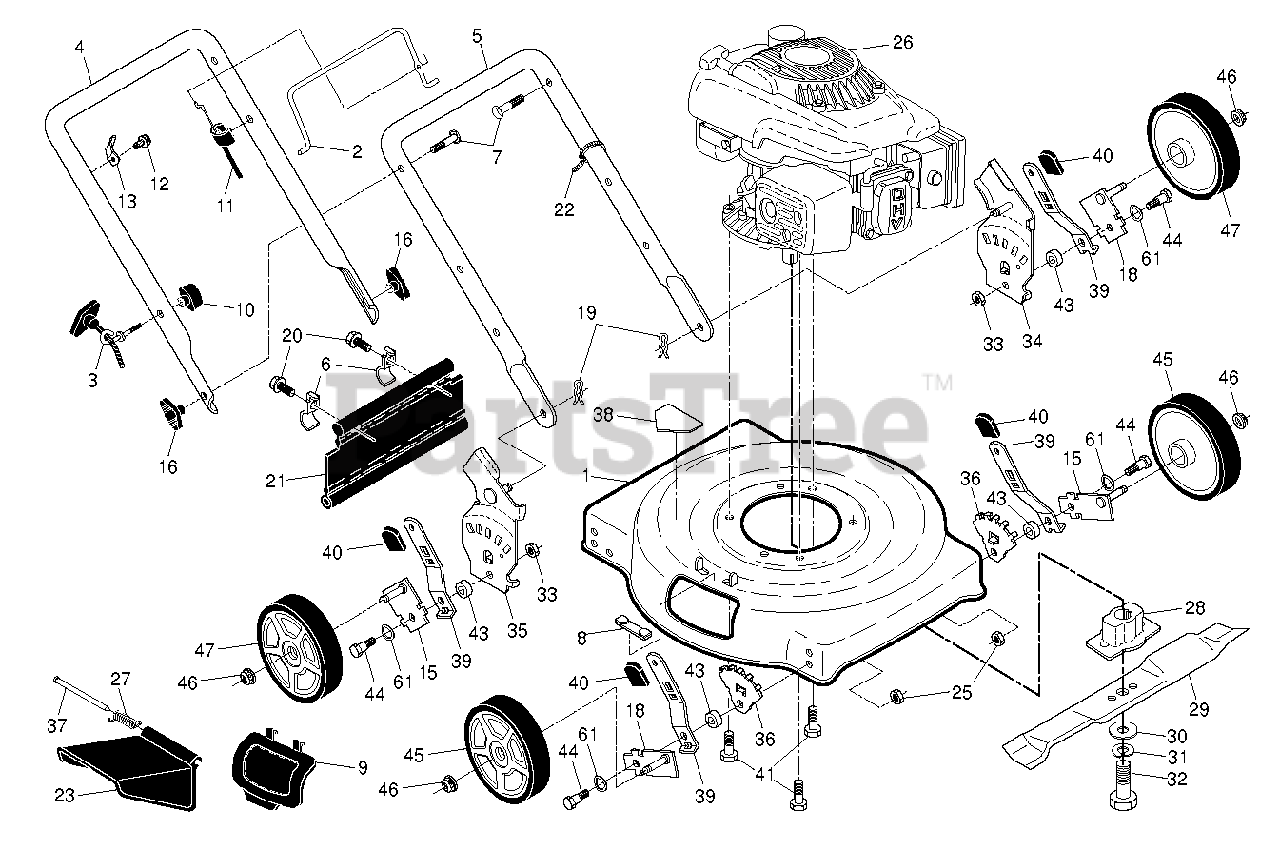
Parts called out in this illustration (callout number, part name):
2	BAIL.CONT.D.STRAIGHT.PUSH.BLK
3	Rope Guide, Blk Zinc Chrom
4	HANDLE.UPPER.ECONOMY.BLACK
5	HANDLE.LOWER.D-STRAIT.BLACK
6	BRACKET.SKIRT.BZP
7	BOLT, HANDLE 5/16-18X1.75
8	CLIP. CLOSEOUT
9	PLATE.MULCHER.22.ECON.BLACK
10	T-KNOB.NEW ROPE GUIDE
11	CABLE.MZR.RATO.22"LOW.
13	BRACKET.UPSTOP.RT
15	AXLE ARM ASSY FRONT LH
18	AXLE ARM ASSY FRONT RH
19	HAIRPIN COTTER
20	TAPPING SCREW
21	SKIRT.REAR.22RD/SD.FO/VE
22	TIE GUIDE
23	GUARD.DISCHARGE.22".
25	NUT.FLANGE.HEX.5/16X18.BLACK
26	ENGINE.RATO.550S.140C
27	SPRING.HINGE
28	ADAPTER.BLADE.W/KEY.25MM.CE
29	BLADE.22.MULCH.STANDARD
30	WASHER,HARDEN
32	BOLT.3/8-24X1.25 GR8
33	NUT.CENTERLOCK.5/16-
34	BRKT.ASM.COM.HND/ADJ.LT.BLACK
35	BRACKET.ASM.COM.HND/ADJ.RT.BLA
36	WHEEL ADJ BRACKET FRONT
37	HINGE ROD
38	No Step Decal
39	SELECTOR SPRING, FRONT
41	BOLT 3/8-16X1-1/8
43	SPACER.HEIGHT.ADJUSTER
44	SHOULDER BOLT 5/16-18
45	WHEEL.7X1.75.5SPK.BRK.BLACK
46	NUT.HEX.FLANGE.3/8-16.LOCKNUT
47	WHEEL.8X1.75.5.SPK.BRK.BLK.1
61	WASHER.CURVED.CYLINDRICAL
